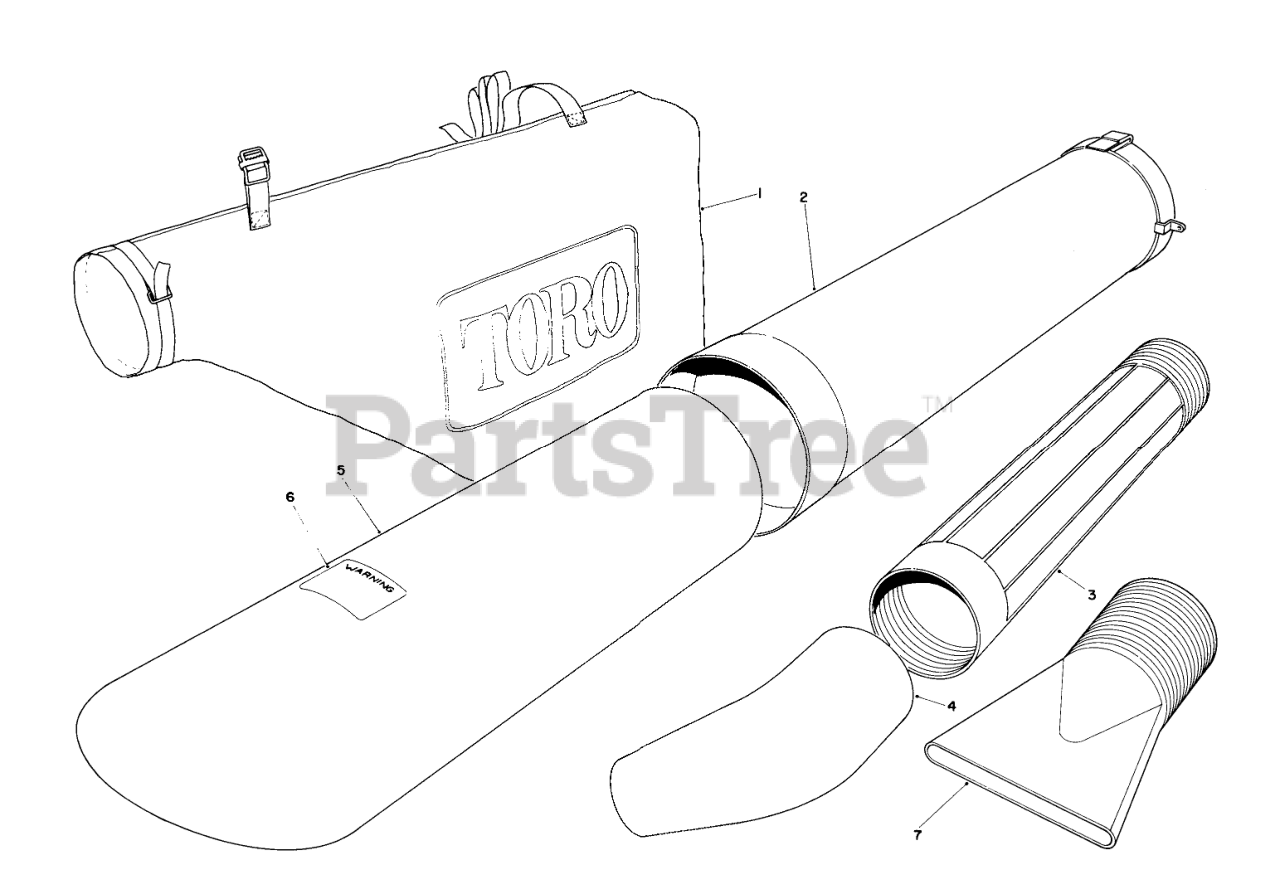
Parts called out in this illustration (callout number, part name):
1	Vacuum Bag
2	Vacuum Tube-Upper
3	Tube
4	Nozzle-Curved
5	Vacuum Tube Assy.-Lower
6	Decal-Warning
7	Nozzle-Diffusing
